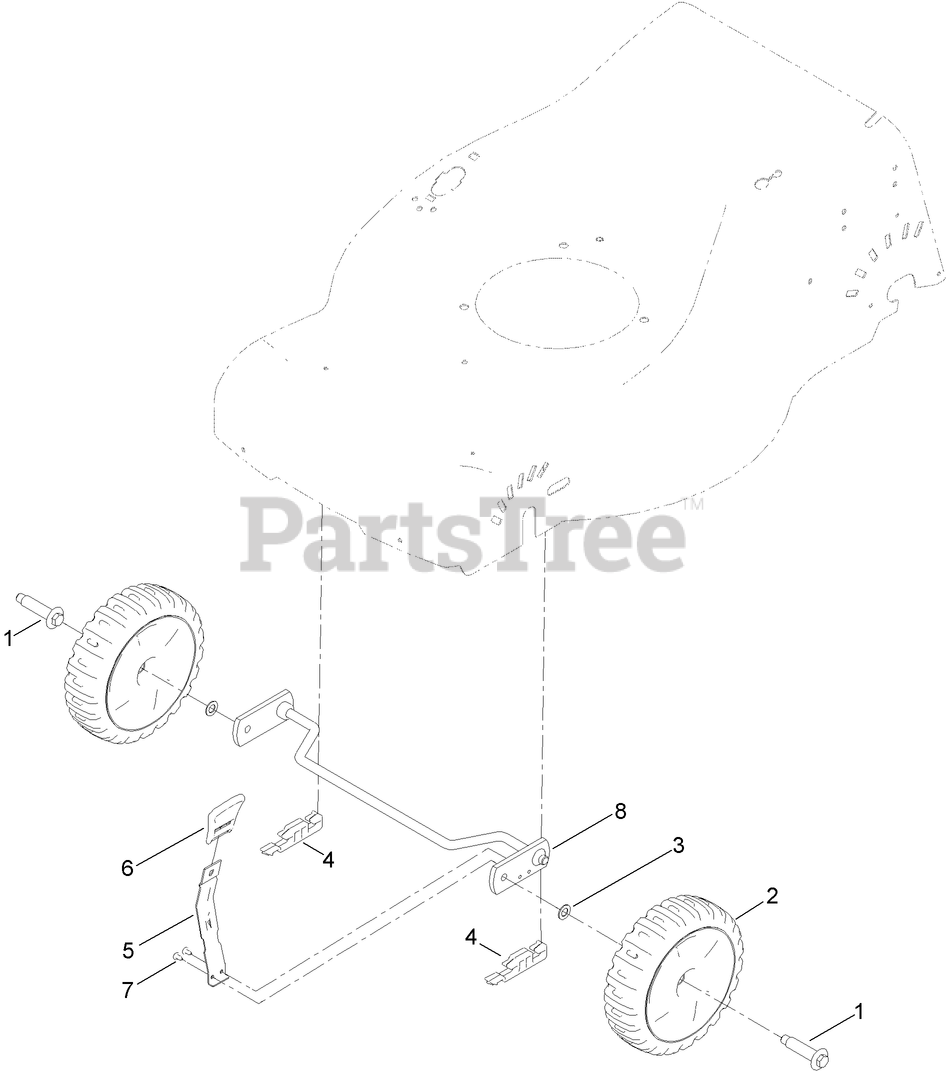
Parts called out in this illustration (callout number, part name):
1	BOLT-SHOULDER
2	7 INCH WHEEL AND TIRE ASM
3	WASHER
4	CLAMP-AXLE, FRONT
5	ARM-SPRING
6	KNOB-HOC
7	SCREW-PAN HEAD, TAP
8	FRONT PIVOT BAR ASM
